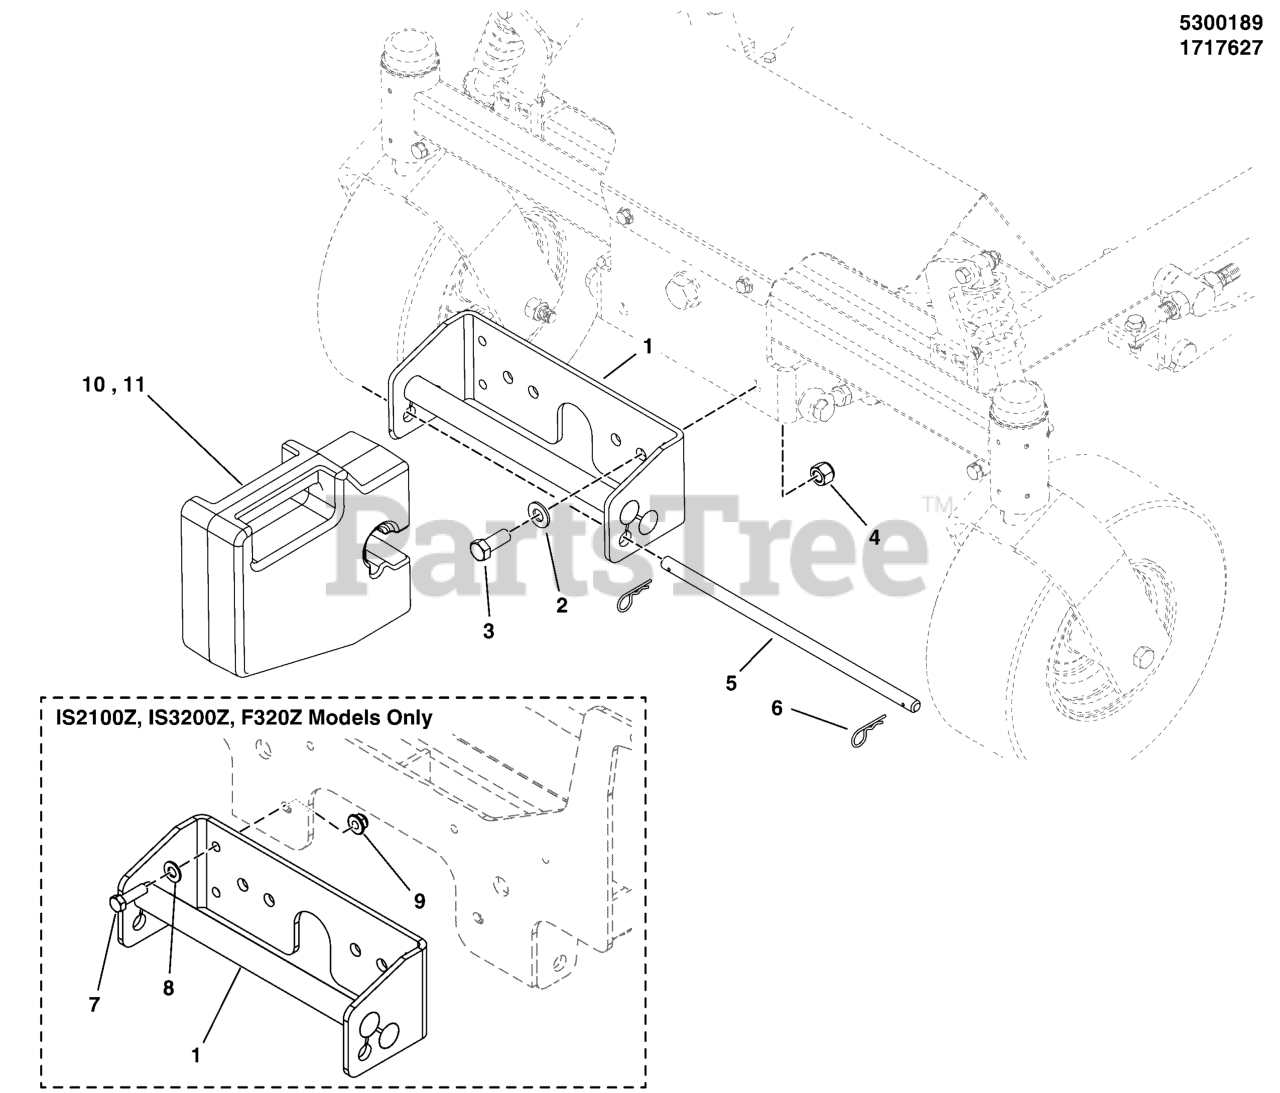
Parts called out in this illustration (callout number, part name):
1	HOLDER ASMY-WEIGHT CONS Z CAT - BLACK
2	WASHER, 1/2 SAE
3	BOLT, 1/2-20 X 1-1/4" GD5 CZ
4	NUT, Hex, Nylon Lock, 1/2-20
5	ROD, .500DIA 13.75LG CZ
6	PIN, HAIR, .0915 X 1-7/8
7	BOLT, 3/8-16 X 1-1/4" GD5 CZ
8	WASHER, 3/8 SAE
9	NUT, 3/8-16 HEX NYLOCK FLANGE
10	WEIGHT-QUICK ATTACH 50LB SUITCASE PAINTED
11	WEIGHT-QUICK ATTACH 50LB SUITCASE PAINTED
